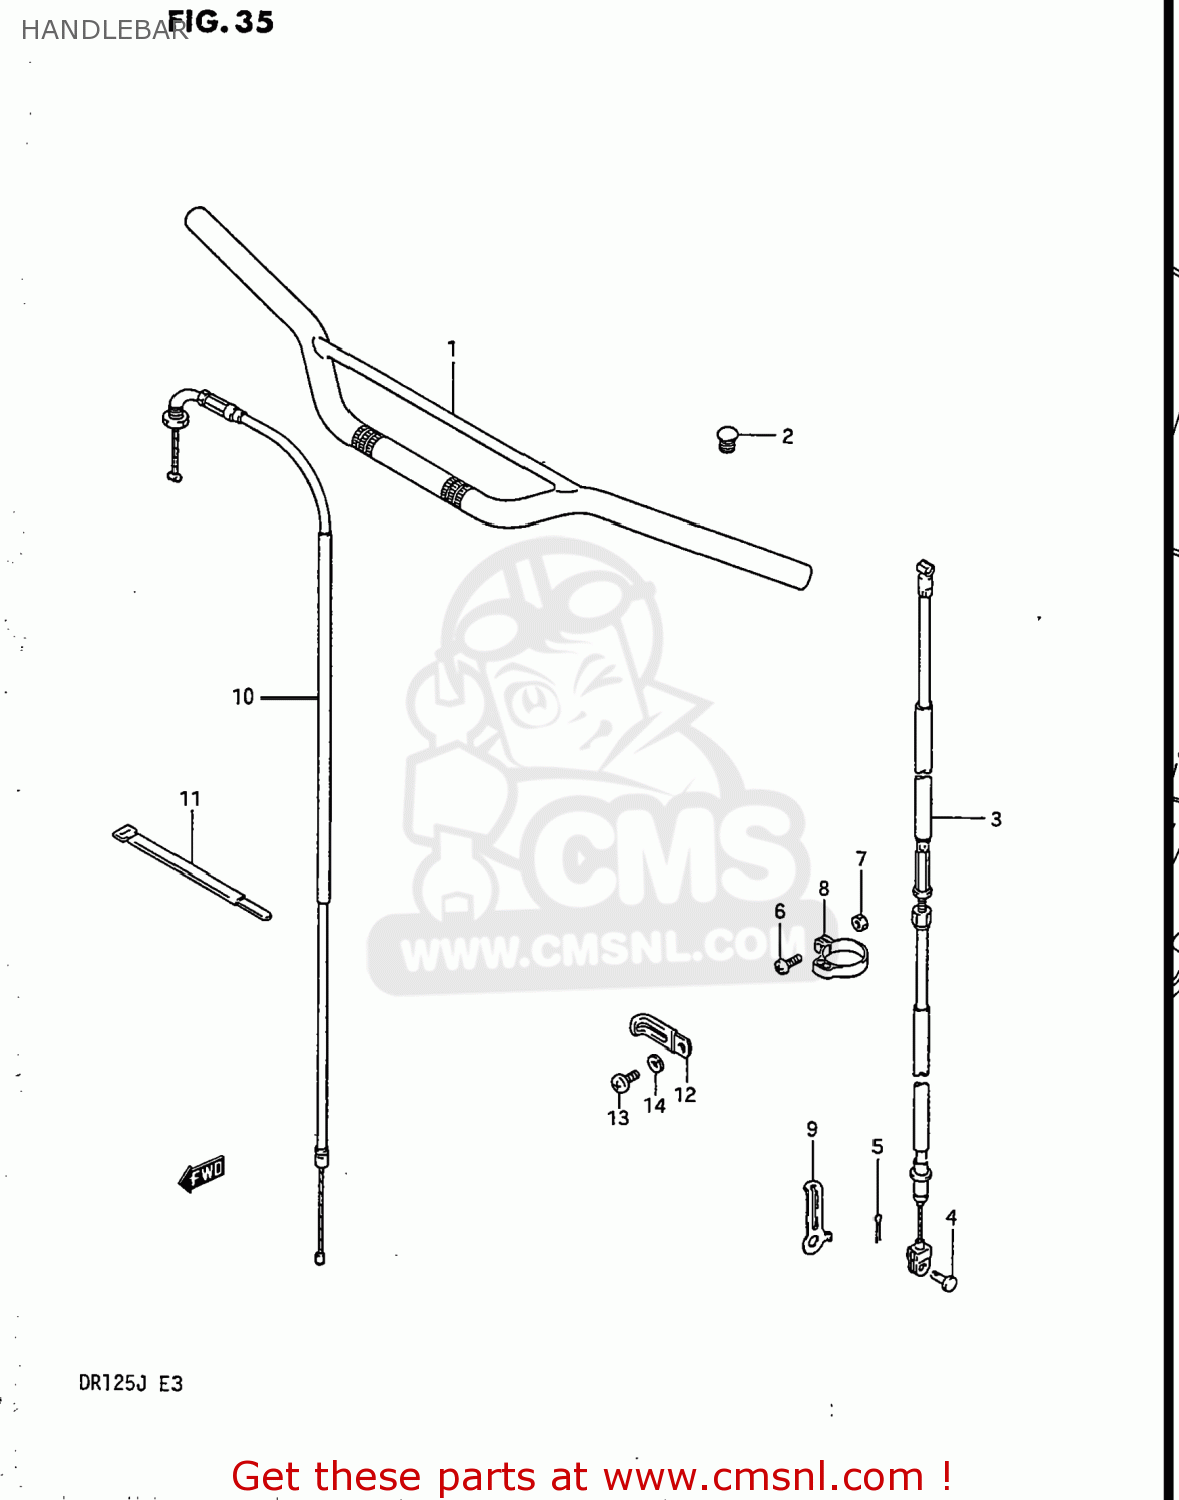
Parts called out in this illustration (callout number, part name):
1	HANDLEBAR
2	CAP(OD:14)
3	CABLE ASSY,CLUTCH
4	PIN(L:15)
5	PIN
6	SCREW
7	NUT 5MM
8	CLAMP,CABLE
9	CLAMP,CABLE
10	CABLE ASSY,THROTTLE
11	CLAMP
12	CLAMP
13	SCREW 6X12
14	WASHER,LOCK
